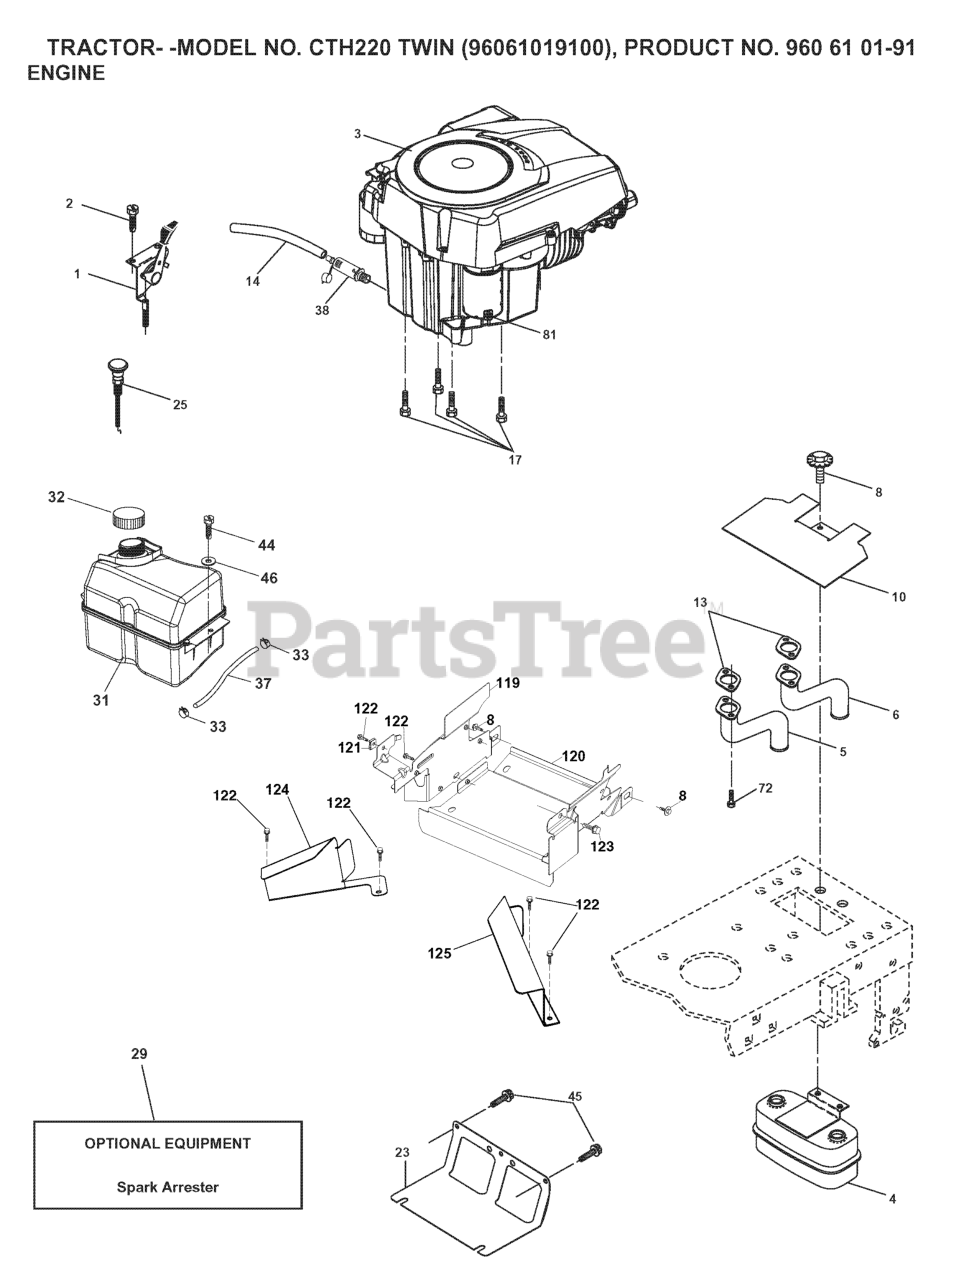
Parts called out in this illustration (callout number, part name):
1	THROTTLE CONTROL
2	SCREW
4	MUFFLER.TWIN.CYL.LOW.TONE
5	RP.PIPE-EXHAUST LH
6	RP.PIPE-EXHAUST RH
8	BOLT.5/16-18UNCX3/4 W/SEMS.BLK
10	RP SHIELD HEAT MUFFLER
14	TUBE, DRAIN OIL ASM.
17	SCREW 3/8-16X1
23	SHIELD.BROWNING.DBR.GUARD
25	CONTROL, CHOKE
29	KIT.SPARK ARRESTOR 794945 B&S
31	TANK.ASM.FUEL.FR.2.5GA.
32	FUEL CAP
33	HOSE CLAMP
37	LINE.FUEL.20
38	PLUG DRAIN OIL EASY
44	SCREW HEXWSHR 1/4-20X3/4
45	SCREW, 3/8-16X3/4
72	SCREW.SOCKET HD.5/16-1
81	NUT
119	LENKRAD
120	GUARD 532199767
122	SCREW.1/4-20X5/8
123	SCREW, 5/16-18 X 1/2
